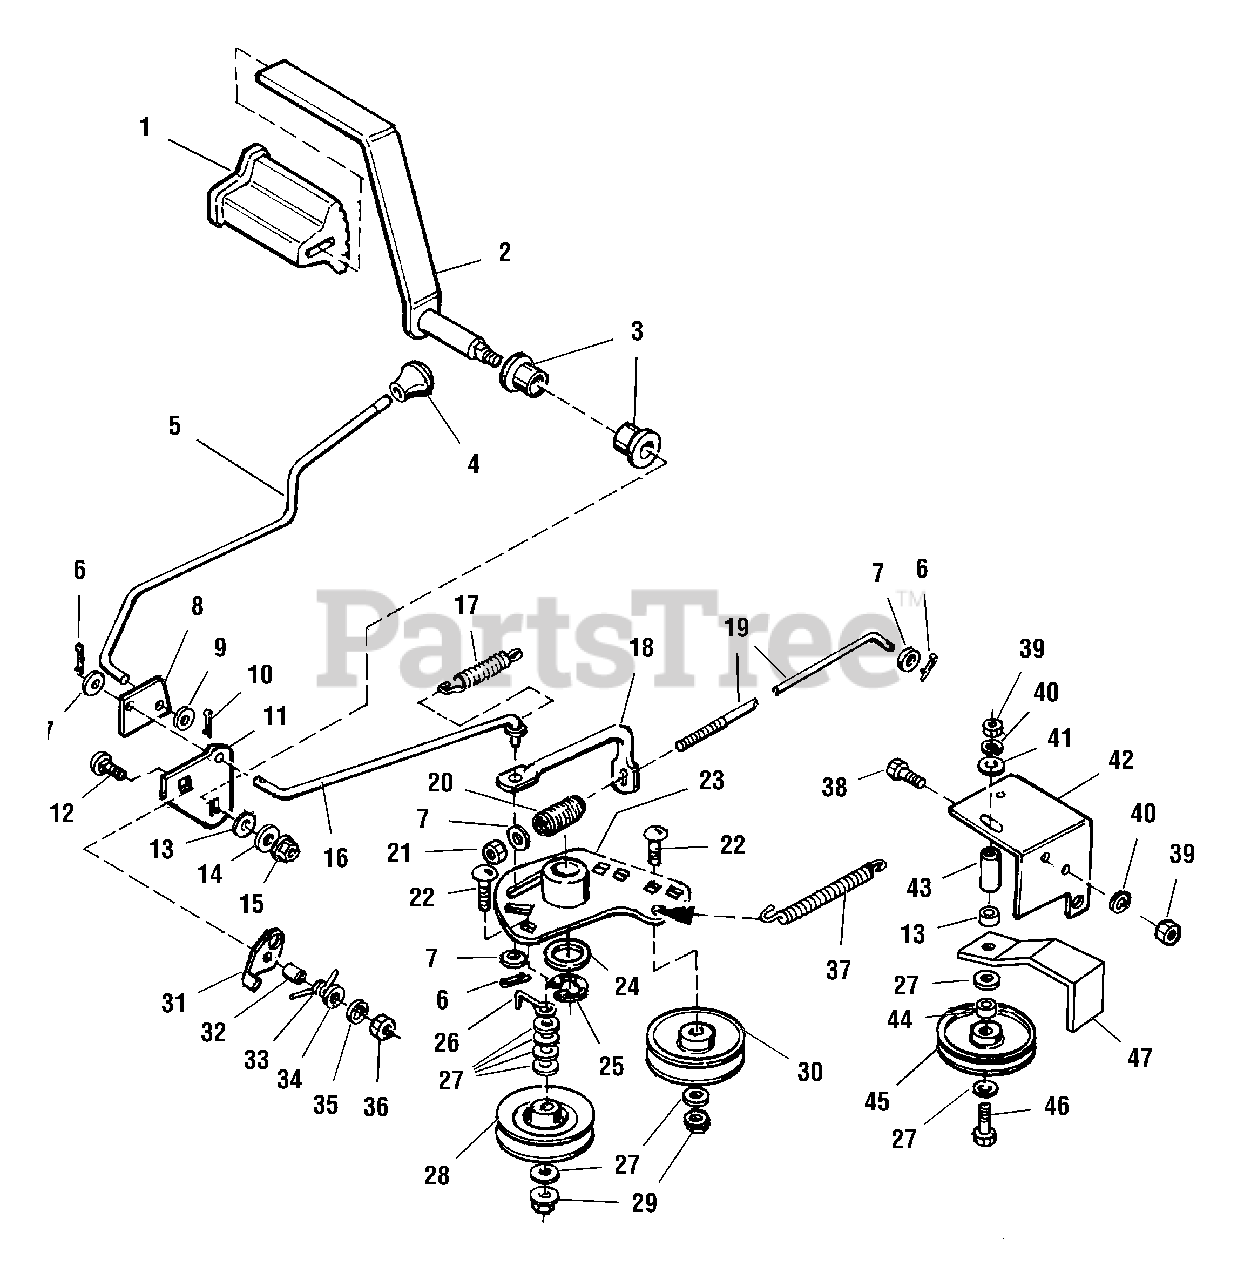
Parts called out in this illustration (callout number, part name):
1	PAD, Brake Pedal Assy.
2	BRAKE PEDAL ASSY.
3	BUSHING, Plastic
5	ROD, Parking Brake
6	COTTER PIN
7	WASHER, Plain, 5/16
8	CAM, Parking Brake
9	WASHER, Plain, 1/4
10	COTTER PIN, 1/16 x 3/4
11	ARM, Brake Pedal Assy.
12	CARRIAGE BOLT, 5/16-18 x 1-1/4
13	WASHER, Plain, 3/8
14	WASHER, 13/32 x 1-1/4 x 1/16
15	NUT, Hex Nyloc, 5/16-18
16	ROD, Clutch
17	SPRING, Extension
18	ARM ASSY., Brake
21	NUT, Hex, Esna, 3/8-16
22	CARRIAGE BOLT, 3/8-16 x 1-3/4
23	IDLER ARM ASSY.
24	WASHER, 5/8 I.D. x 1-1/4 O.D. x 5/64 Thk.
25	KLIP RING, 5/8
27	WASHER, Plain, 3/8
28	PULLEY, V, Idler
29	NUT, Hex, Flange, Whiz, 3/8-16
30	PULLEY, Idler, Backside
31	SWITCH, Actuator
33	SPRING, Tension
34	WASHER, 21/64 I.D. x 1-1/4 O.D. x 5/64 Thk.
35	LOCKWASHER, 5/16
36	NUT, Hex, Full, 5/16-18
37	SPRING, Drive
38	CAPSCREW, Hex Hd., 3/8-16 x 1
39	NUT, Hex, 3/8-16
40	LOCKWASHER, 3/8
41	WASHER, Plain, 3/4
42	BRACKET, Idler
43	SPACER, 25/64 x 1 x 1-7/32
44	SPACER, 3/8 x 43/64 x 29/64
46	CAPSCREW, Hex Hd., 3/8-16 x 3-1/4
47	GUARD, Spring "L"
